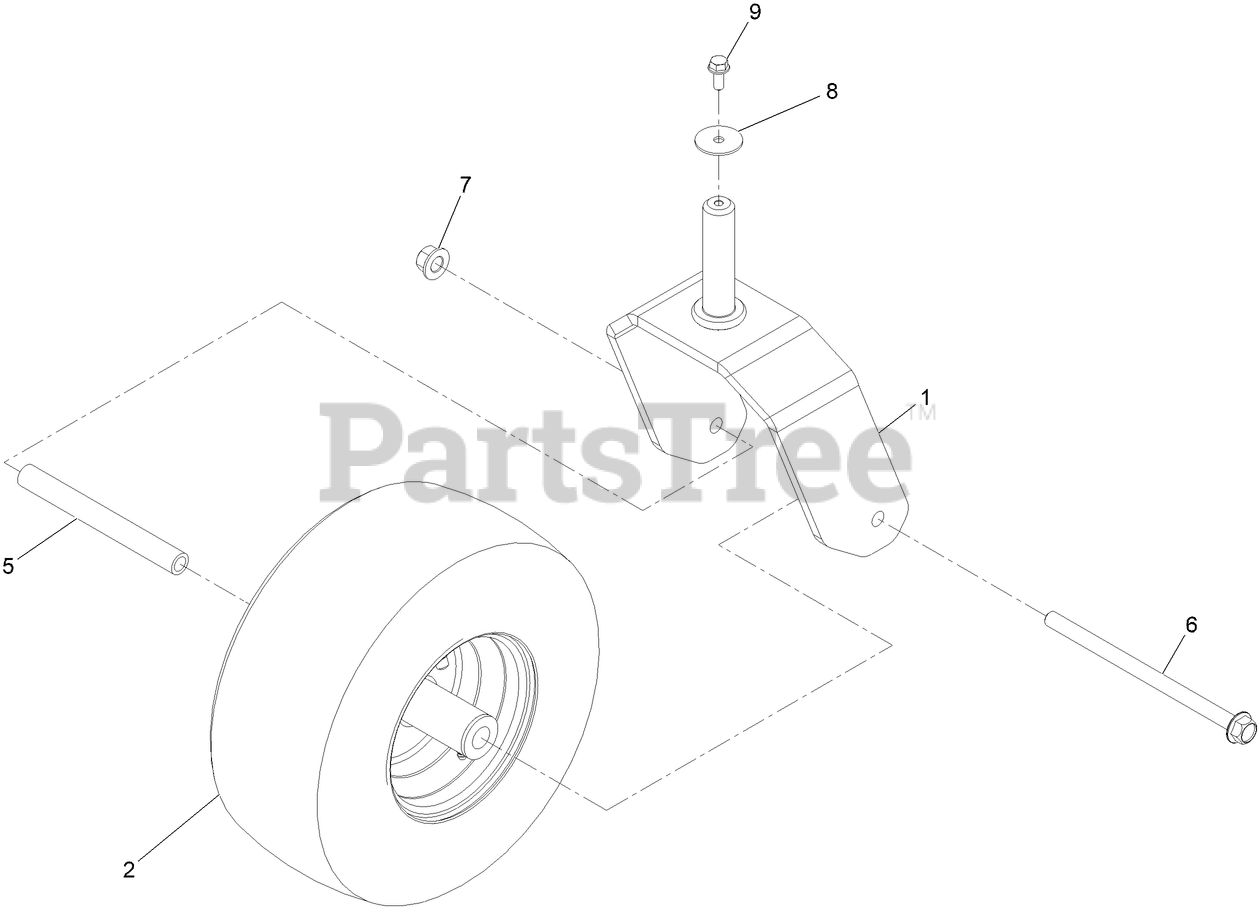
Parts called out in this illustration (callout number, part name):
1	CASTER-FORK
2	ASM, TIRE & WHEEL
5	SPANNER-WHEEL
6	SCREW-HHF
7	Nut-Lock 1/2-13
8	WASHER-FLAT
9	SCREW-HHF
